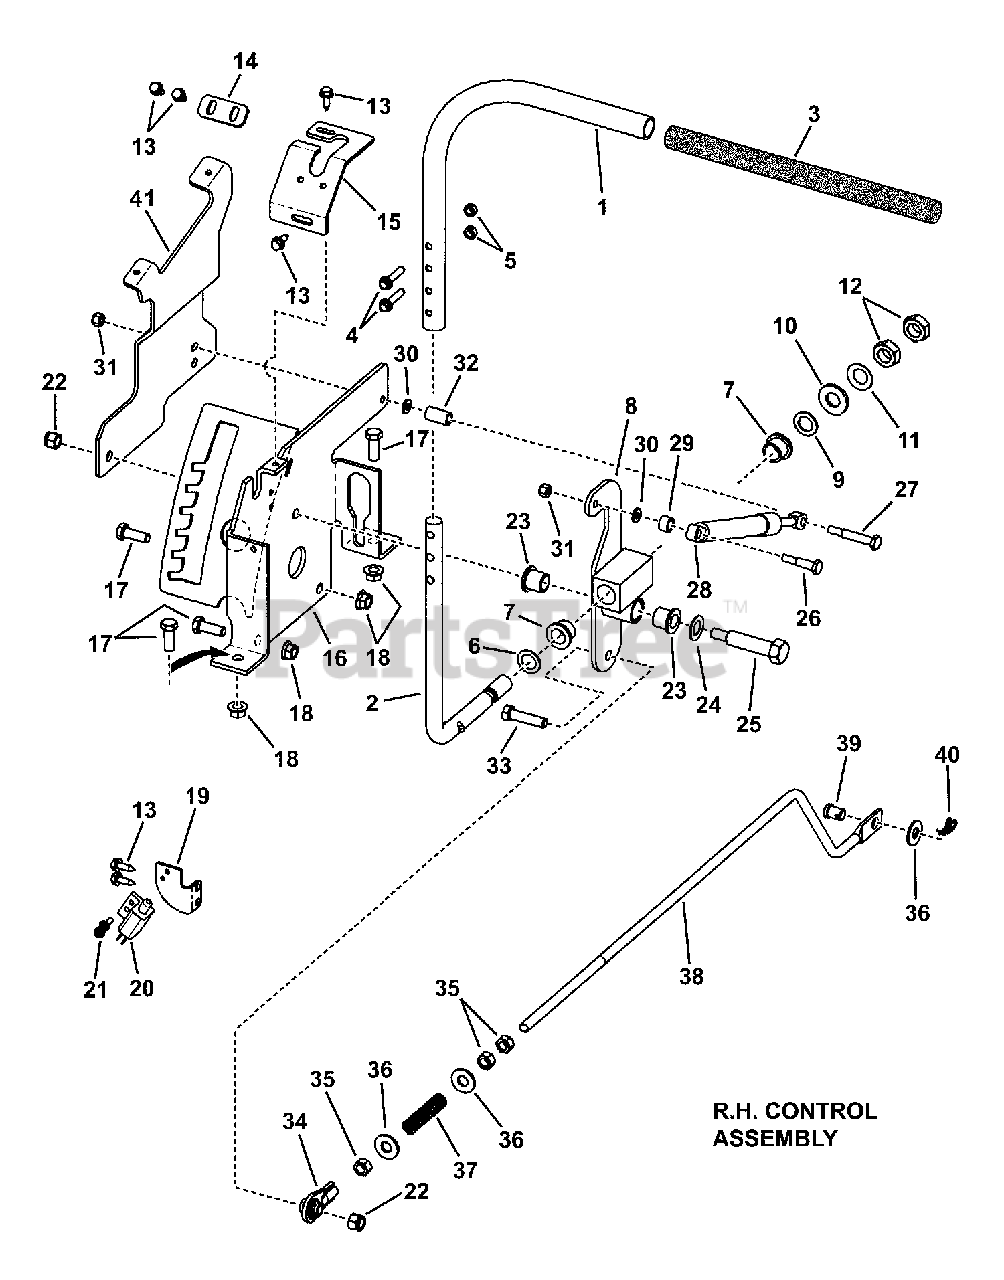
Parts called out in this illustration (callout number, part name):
1	HANDLE
2	ROD, Handle R.H. (5/8" dia. Rod)
3	FOAM GRIP, Handle
4	SCREW, 1/4-20 x 1-1/4" Hex Head Cap, GR 5
5	NUT 1/4-20 Hex Center Lock, GR 5 YZ
6	WASHER, .64 x .99 x .05 Flat, YZ
7	BUSHING, Bronze, 5/8 x 5/8"
8	WELDMENT, Control Arm, RH
9	WASHER, 5/8 ID x 1.00 OD x .065 Nylon
10	WASHER, 5/8 SAE Flat
11	WASHER, .64 x 1.12 x .028 Beveled
12	NUT, 5/8-18 Hex Jam
13	SCREW, 1/4-20 x 3/4" Hex Washer Self-Tap
14	PLATE, Fwd/Rev Adjust
15	TRACK, Control Stick, R.H.
16	WELDMENT, Lift Bracket
17	SCREW, 3/8-16 x 1" Hex Head Cap, GR 5, YZ
18	NUT, 3/8-16 Hex Flange Lock
19	BRACKET, Switch
20	SWITCH- DPDT
21	SCREW, #10-24 x 1/2" Hex Washer Self-Tap (Torx)
22	NUT, 3/8-16 Hex Nyloc
23	FLANGE BEARING, 9/16 I.D. P.M.
24	THRUST WASHER, .562 ID x 1.000 OD x .030/.032 Thick
25	SHOULDER BOLT, 3/8-16
26	SHOULDER BOLT, 5/16 x 1/4-20
27	SHOULDER BOLT, 5/16 x 1/4-20
28	DAMPENER, Hydraulic
29	SPACER, 9/16 OD x 12GA x .325
30	WASHER, 1/4" I.D. Flat
31	NUT, 1/4-20 Hex Nyloc
32	SPACER, 9/16 OD x 12GA x .899
33	SCREW, 3/8-16 x 1-1/2" Hex Head Cap, GR 5
34	ROD END
35	NUT, 3/8-24 Hex, GR B, YZ
36	WASHER, 7/16" Flat
37	SPRING, Compression (Brake)
38	ROD, Link Fwd./Rev. (3/8-24 thread)
39	CLEVIS PIN, 7/16 x 1"
40	COTTER PIN, 1/2 Self Locking, YZ
41	BRACKET, Fender Support, RH
